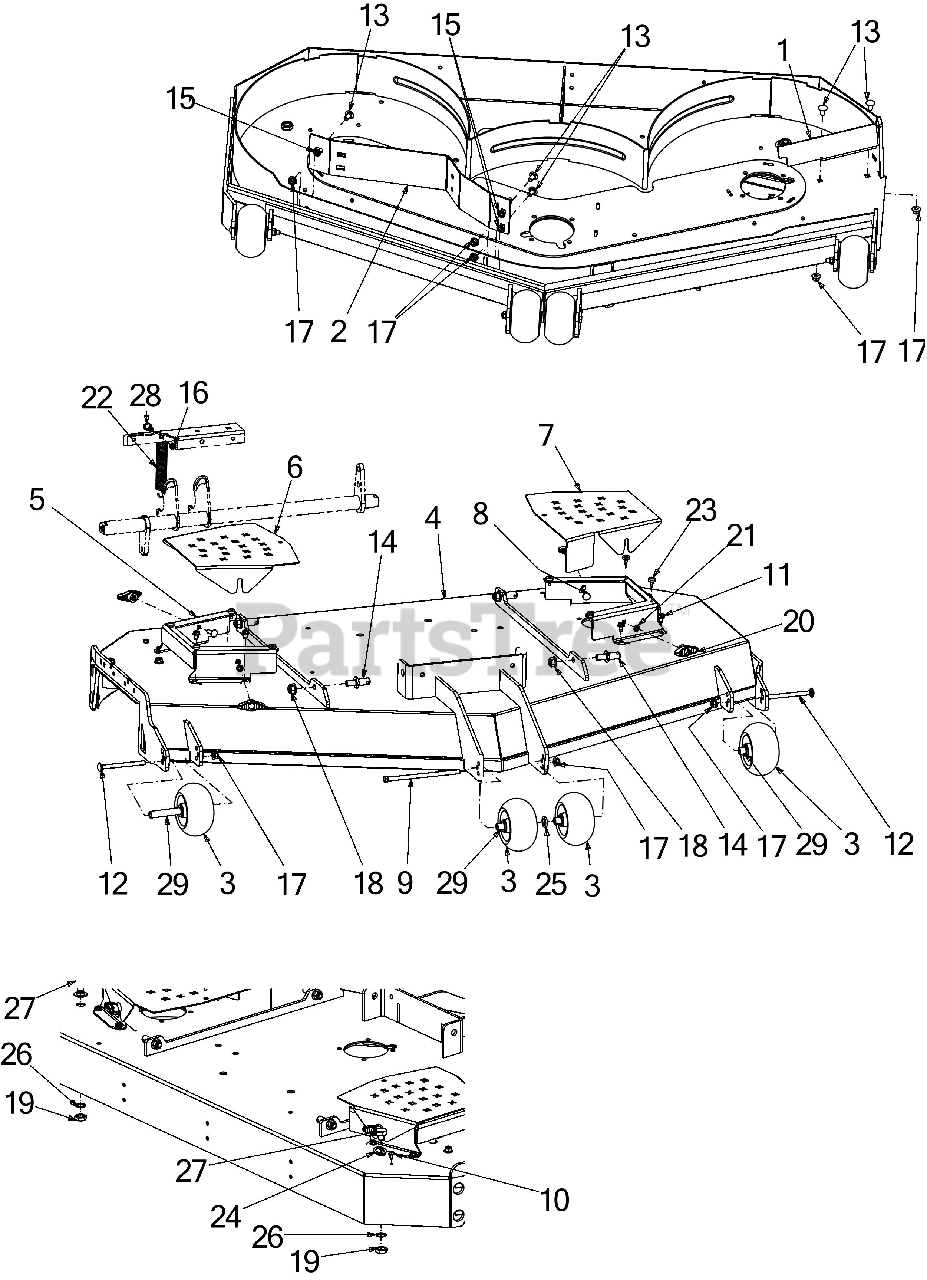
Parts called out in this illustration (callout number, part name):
3	WHEEL ASSEMBLY 5"
4	60" DECK ASSEMBLY
5	DECK BELT COVER BRACKET
6	DECK BELT COVER
7	DECK BELT COVER (LH)
8	CARRIAGE BOLT 5/16-18 x 1.00
9	SCREW 3/8-16 x 7.25 GR5
10	SCREW 1/4-20 X.500
11	SCREW 5/16-18 x .500
12	CARRIAGE BOLT 3/8-16 x 4.25 GR5
13	CARRIAGE BOLT 3/8-16 x .75
16	FLANGE LOCK NUT
19	HEX NUT
20	WING KNOB 5/16-18
22	EXTENSION SPRING
23	BUMPER, .62 DIA x .3
24	FLAT WASHER .793ID x 1.24OD x .060
25	FLAT WASHER .632X1.00X.16
26	LOCK WASHER
27	DECK WASH PLUG
28	SHOULDER SCREW .437X.50 1/4-20
29	WHEEL SPACER .38ID x 3.04LG
